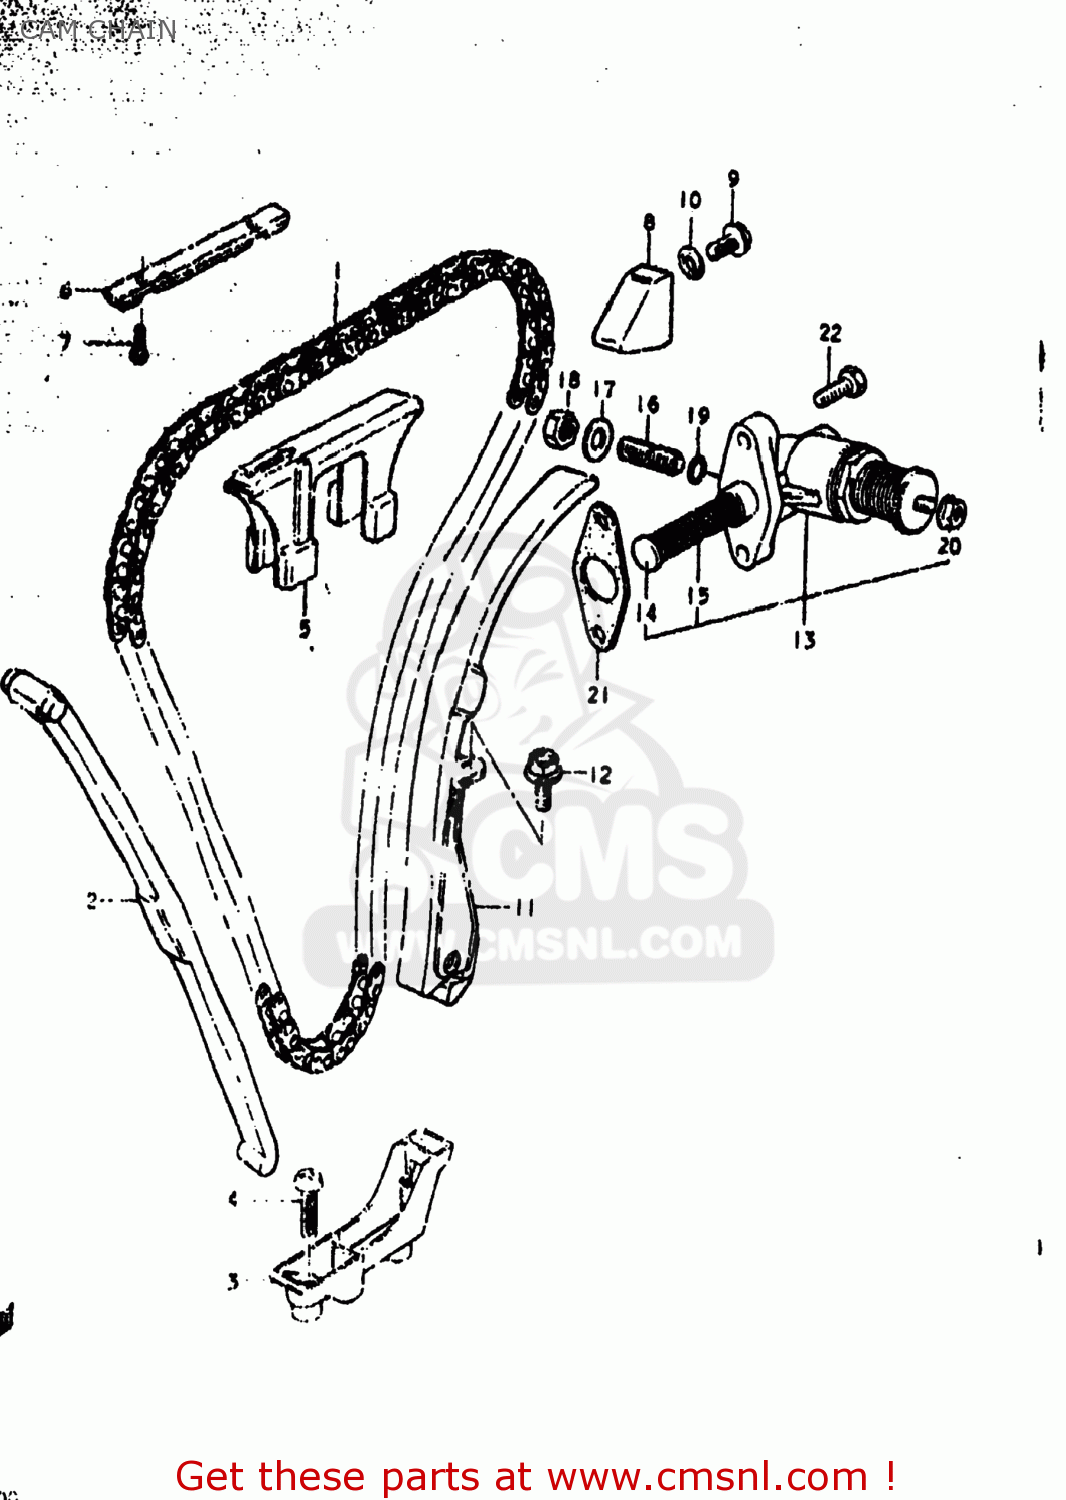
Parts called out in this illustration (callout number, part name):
1	CHAIN,CAMSHAFT DRIVE
2	GUIDE,CAM CHAIN
3	HOLDER,CAM CHAIN GUIDE
4	SCREW
5	GUIDE,CAM CHAIN NO.2
6	GUIDE,CAM CHAIN NO.3
7	SCREW
8	GUIDE,CAM CHAIN
9	BOLT
10	GASKET (NAS)
11	TENSIONER,CAM CHAIN
12	BOLT
13	ADJUSTER ASSEMBLY,TENSIONER
14	ROD,PUSH
15	SPRING
16	SCREW
17	WASHER
18	NUT
19	O-RING
20	NUT
21	GASKET,TENSIONER ADJUSTER (MCA)
22	SCREW
